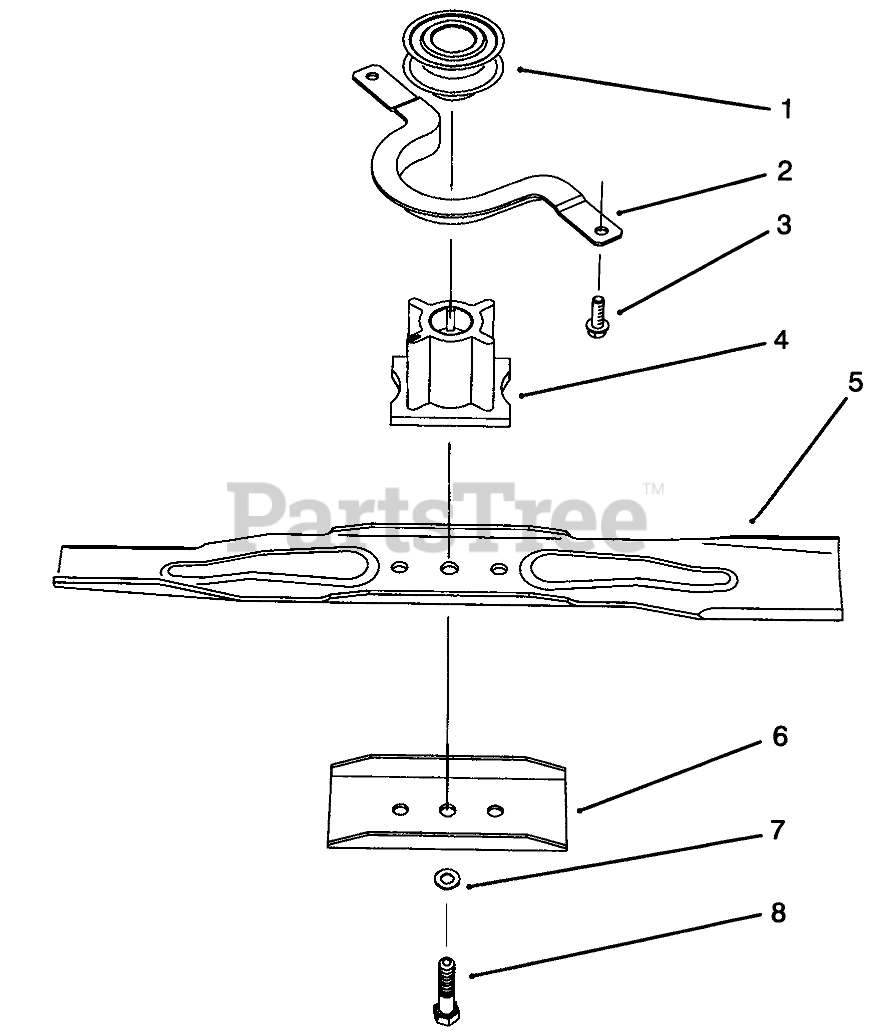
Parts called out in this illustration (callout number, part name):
1	PULLEY-DRIVE, ZONE START
2	Guide-Belt
3	SCREW-HWH
4	BLADE RETAINER - 25 MM
5	Blade
6	Stiffener
7	WASHER-LOCK
8	BOLT-BLADE
